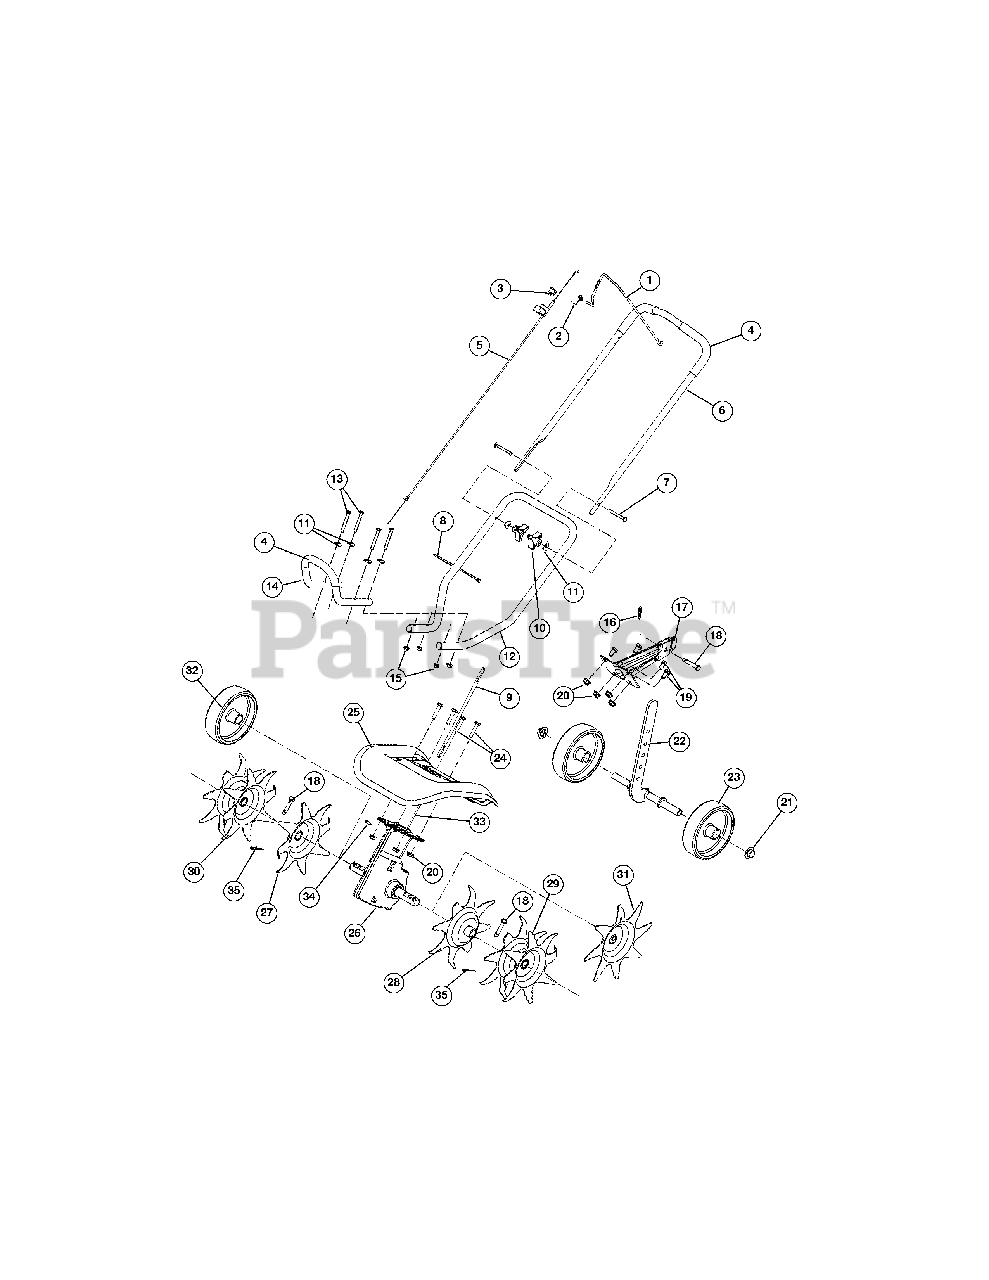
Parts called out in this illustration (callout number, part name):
1	Throttle Control
2	Torsion Spring
3	On/Off Switch
4	Foam Grip
5	Throttle Cable
6	Upper Handle
8	Cable Tie
9	Flex Shaft
11	Shoulder Washer
13	Screw
14	Front Handle
16	Clip
17	Tailpiece Bracket Assembly
18	Cotter Pin
19	Cap Screw
22	Wheel Support Bracket Assembly
23	Wheel
24	Cap Screw
25	Tine Shield
26	Gear Box Assembly
27	Tine (Right Inner)
28	Tine (Left Inner)
29	Tine (Left Outer)
30	Tine (Right Outer)
31	Edger Tine
32	Edger Wheel
33	Drive Shaft Housing
34	Sleeve Retaining Bolt
